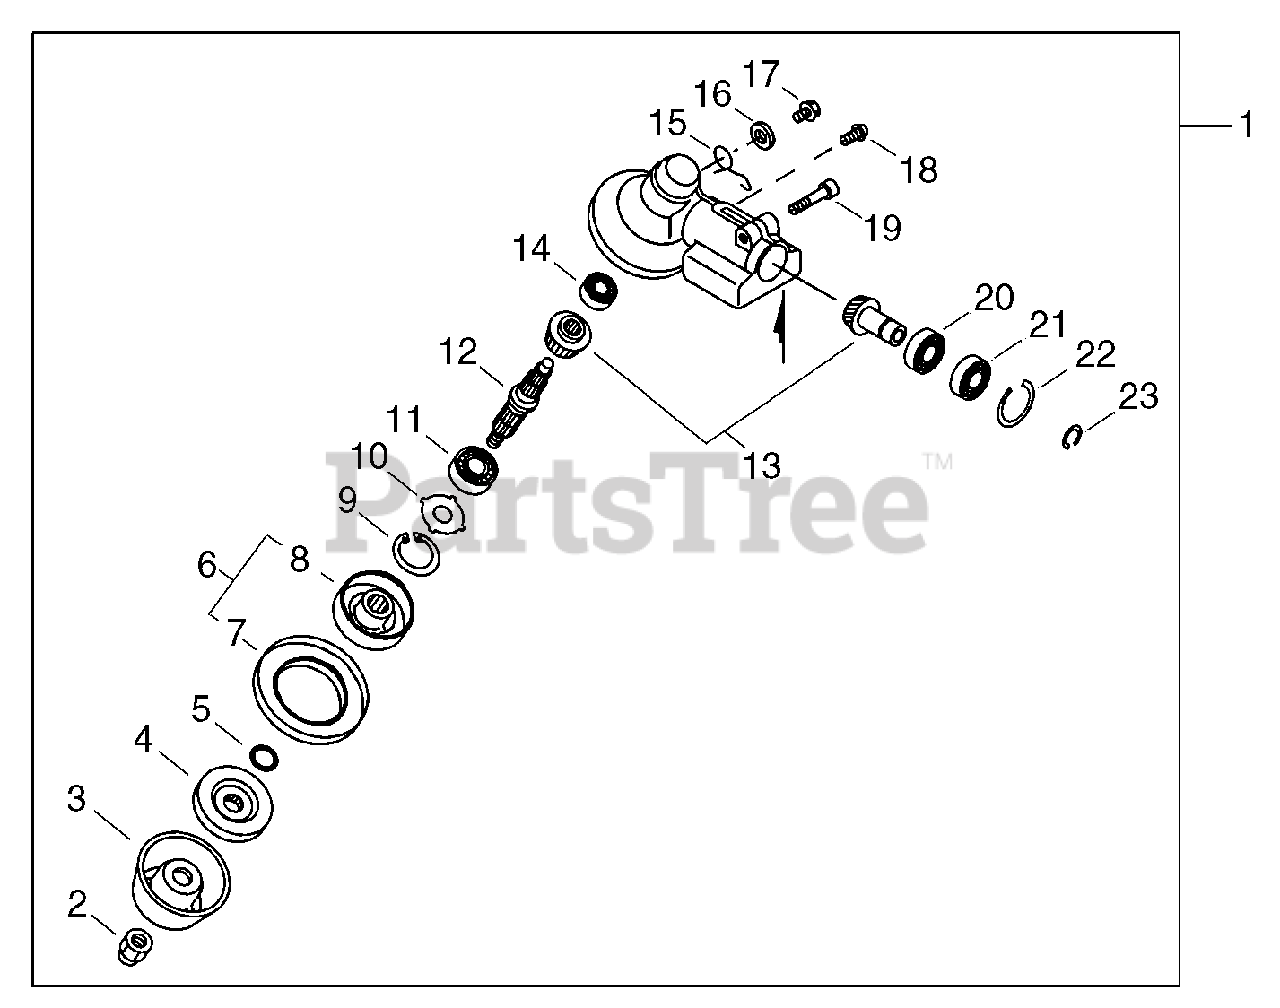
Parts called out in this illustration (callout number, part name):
1	GEAR CASE ASSY
2	NUT, LOCK 10 - NYLON INSERT
4	PLATE, ADAPTOR - LOWER
5	O-RING 12 MM
6	RETAINER ASSY, BLADE
7	PLATE, ADAPTOR - LOWER
8	RETAINER, BLADE
9	RING, SNAP Ø32
11	BEARING, BALL 6201
12	SHAFT, GEAR
13	GEAR SET, BEVEL
14	BEARING, BALL 626
15	SPRING, TORSION
16	WASHER 8.5×18×0.8T
17	BOLT M8×8
18	SCREW 5×10
20	BEARING, BALL 6900
21	BEARING, BALL 6900Z
22	RING, SNAP Ø22
23	RING, SNAP Ø10
